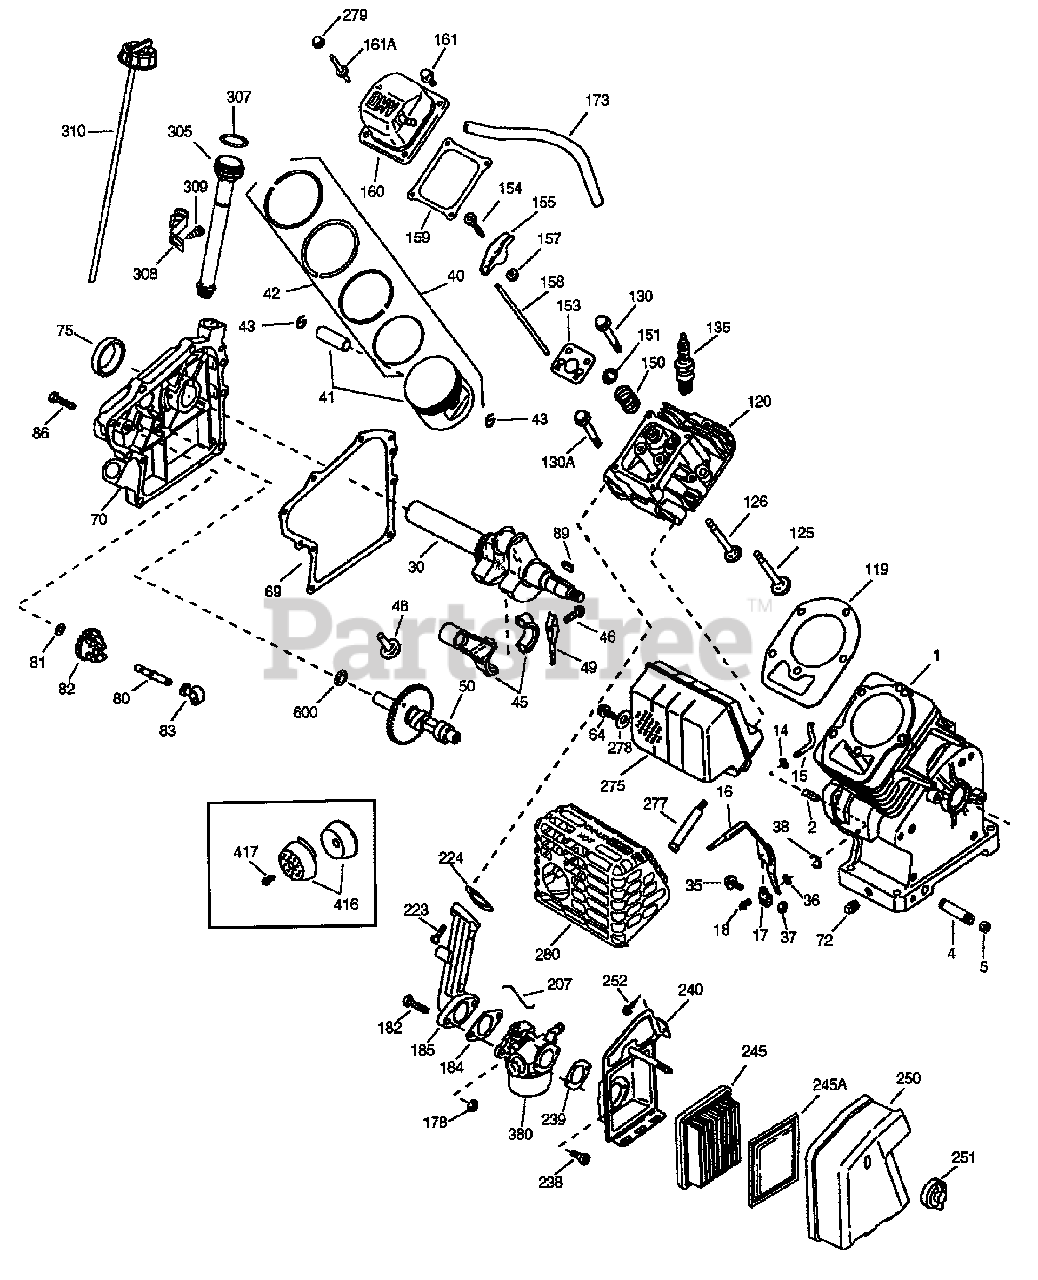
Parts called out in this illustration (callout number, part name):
2	Dowel Pin
4	Oil Drain Extension
5	Extension Cap
15	Governor Rod
16	Governor Lever
17	Governor Lever Clamp
18	Screw, Torx T-15, 8-32 x 3/8"
30	Crankshaft
35	Screw, 10-32 x 3/4"
36	Lock Washer
37	Lock Nut, 10-32
38	Retaining Ring
40	Piston, Pin & Ring Set (Std)
41	Piston & Pin Assy (Std)
42	Ring set (Std)
43	Piston Pin Retaining Ring
45	Connecting Rod Assy
46	Connecting Rod Bolt
48	Valve Lifter
49	Oil Dipper
50	Camshaft
64	Screw, 1/4-20 x 1-1/8"
69	Cylinder Cover Gasket
70	Cylinder Cover
72	Oil Drain Plug
80	Governor Shaft
82	Governor Gear Assy
83	Governor Spool
86	Screw, 1/4-20 x 1-1/4"
89	Flywheel Key
119	Cylinder Head Gasket
120	Cylinder Head
125	Exhaust Valve (Std)
126	Intake Valve (Std)
130	Screw, 5/16-18 x 1-1/2"
130A	Screw, 5/16-18 x 2-41/64"
135	Resistor Spark Plug (N4C)
150	Valve Spring
151	Valve Spring Cap
153	Push Rod Guide
154	Rocker Arm Stud
155	Rocker Arm
157	Nut, 1/4-28
159	Rocker Arm Cover Gasket
160	Rocker Arm Cover
161	Screw, 1/4-20 x 31/64"
173	Breather Tube
178	Nut, 1/4-20
182	Screw, 1/4-20 x 1"
184	Carburetor to Intake Pipe Gasket
185	Intake Pipe
207	Throttle Link
223	Screw, 1/4-20 x 1"
224	Intake Pipe Gasket
238	Screw, 10-32 x 1/2"
239	Air Cleaner Gasket
240	Air Cleaner Body
245	Air Cleaner Filter
245A	Air Cleaner Filter (Poly)
250	Air Cleaner Cover
252	Screw, 10-32 x 1/2"
275	Muffler
277	Screw, 1/4-20 x 2-9/32"
279	Nut & Lock Washer
280	Heat Shield
305	Oil Fill Tube
308	Fill Tube Clip
309	Screw, 10-32 x 5/16"
310	Dipstick
380	Carburetor
416	Spark Arrestor Kit
417	Screw, 8-32 x 3/8"
